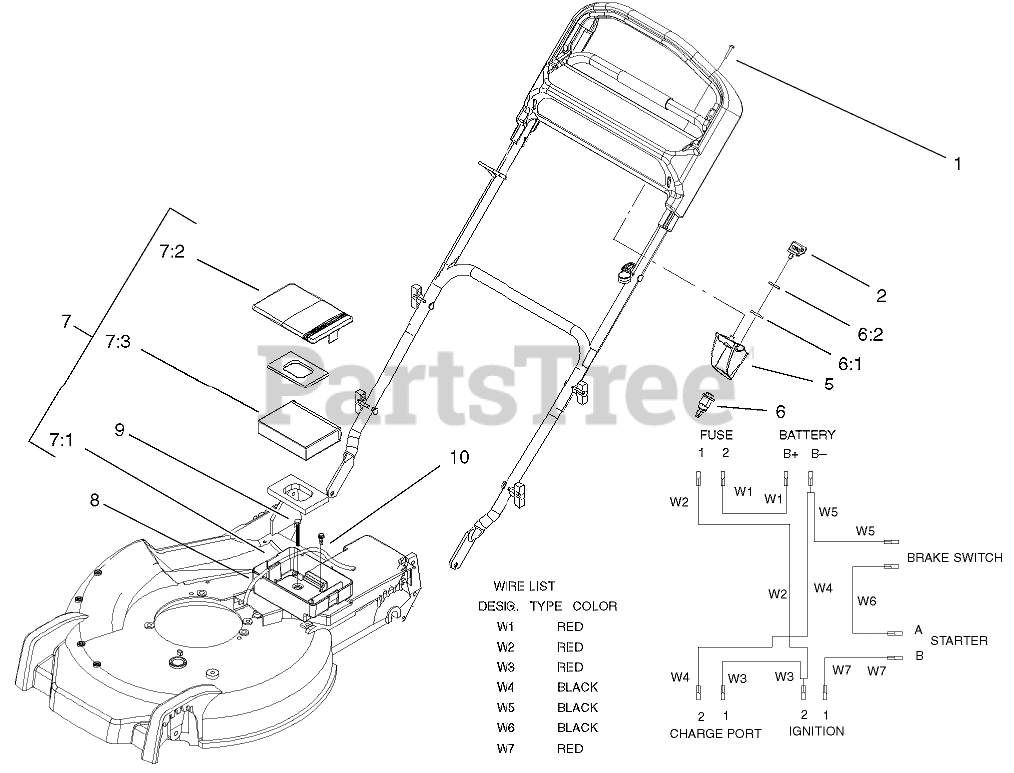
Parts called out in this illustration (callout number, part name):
1	SCREW-PPH, PLASTITE
2	KEY-IGNITION
5	SWITCH-HOLDER
6	STARTER SWITCH ASM
6:1	WASHER-TOOTH, INTERNAL
6:2	NUT-HH
7	BATTERY ASM-PANASONIC
7:1	BOX-BATTERY
7:2	COVER-BATTERY
7:3	BATTERY-12V
8	HARNESS-WIRE,TC
9	SCREW-SPECIAL
